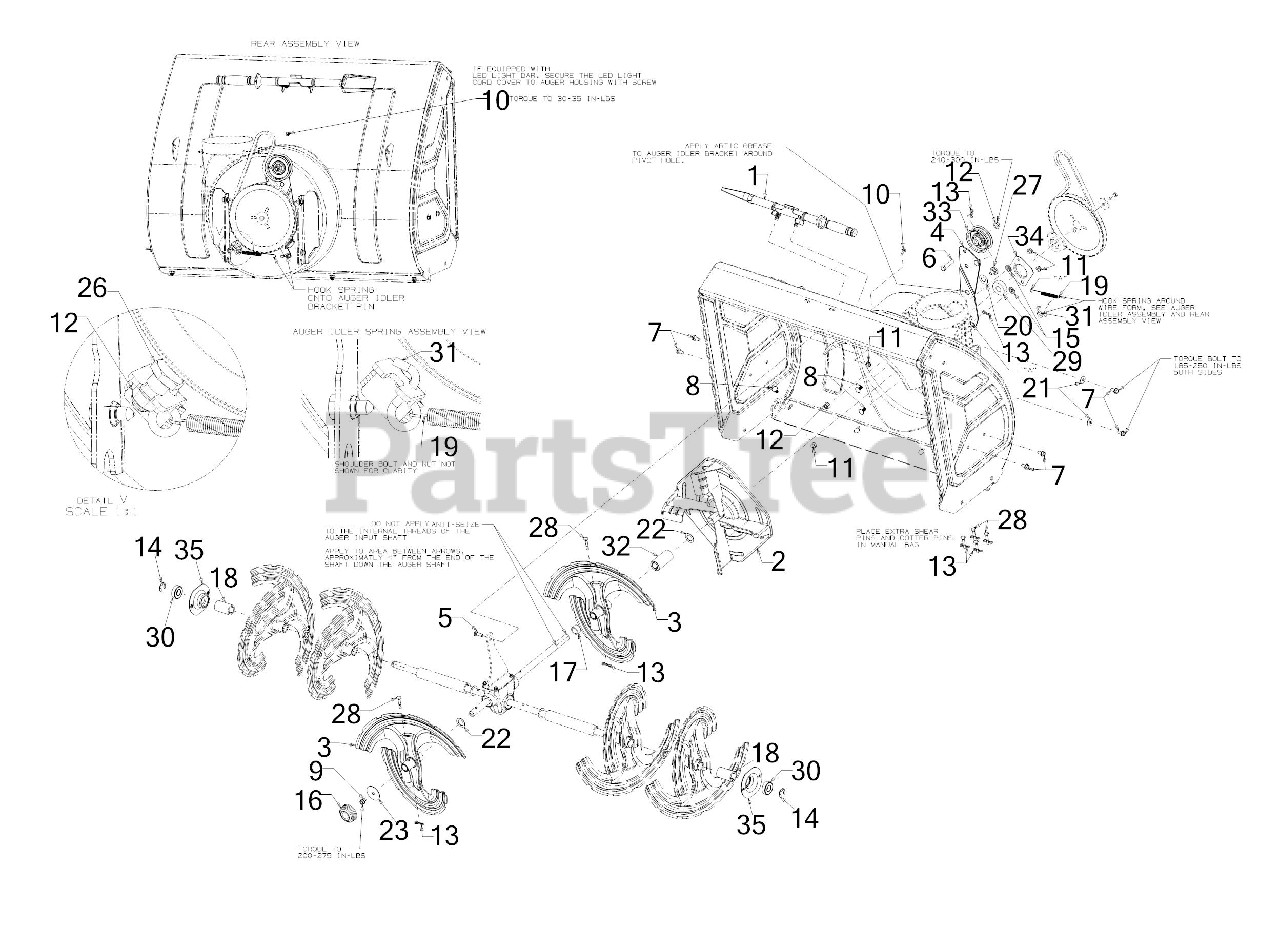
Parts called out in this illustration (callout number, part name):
1	CLEANOUT TOOL
1	CLEANOUT TOOL MOUNTING CLIP
2	4 BLADE IMPELLER 14.5 DIA
4	AUGER IDLER BRACKET
5	CARRIAGE BOLT 5/16-18 x 1.00
6	HEX SCREW 3/8-16 x 1.75 GR5
7	SCREW 5/16-18 x .750
8	CARRIAGE BOLT 5/16-18 x .75
9	SCREW 5/16-18 x .500
10	SCREW M6-1 x .625
11	FLANGE LOCK NUT 5/16-18
13	BOW TIE COTTER PIN 1/4-5/16
14	E-RING
15	PUSH ON NUT
16	CASTER AXLE CAP
18	SPACER 1.25 x .75 x 2.085
19	EXTENSION SPRING .38 OD x 4.59
20	FLAT WASHER
21	BELL WASHER .337 X.867 x .057
22	FLAT WASHER .793ID x 1.24OD x .060
23	HUB CAP WASHER .406 x 1.92 x .060
26	SHOULDER SCREW .498 DIA x .340
27	SHOULDER SCREW .625
28	SHEAR PIN .25 x 1.50 GR2
29	FLANGE BEARING
30	BALL BEARING
31	ROD SPRING HOOK
33	FLAT IDLER PULLEY 2.75 OD
34	BEARING HOUSING 1.85 ID
35	BEARING HOUSING 1.59 ID
